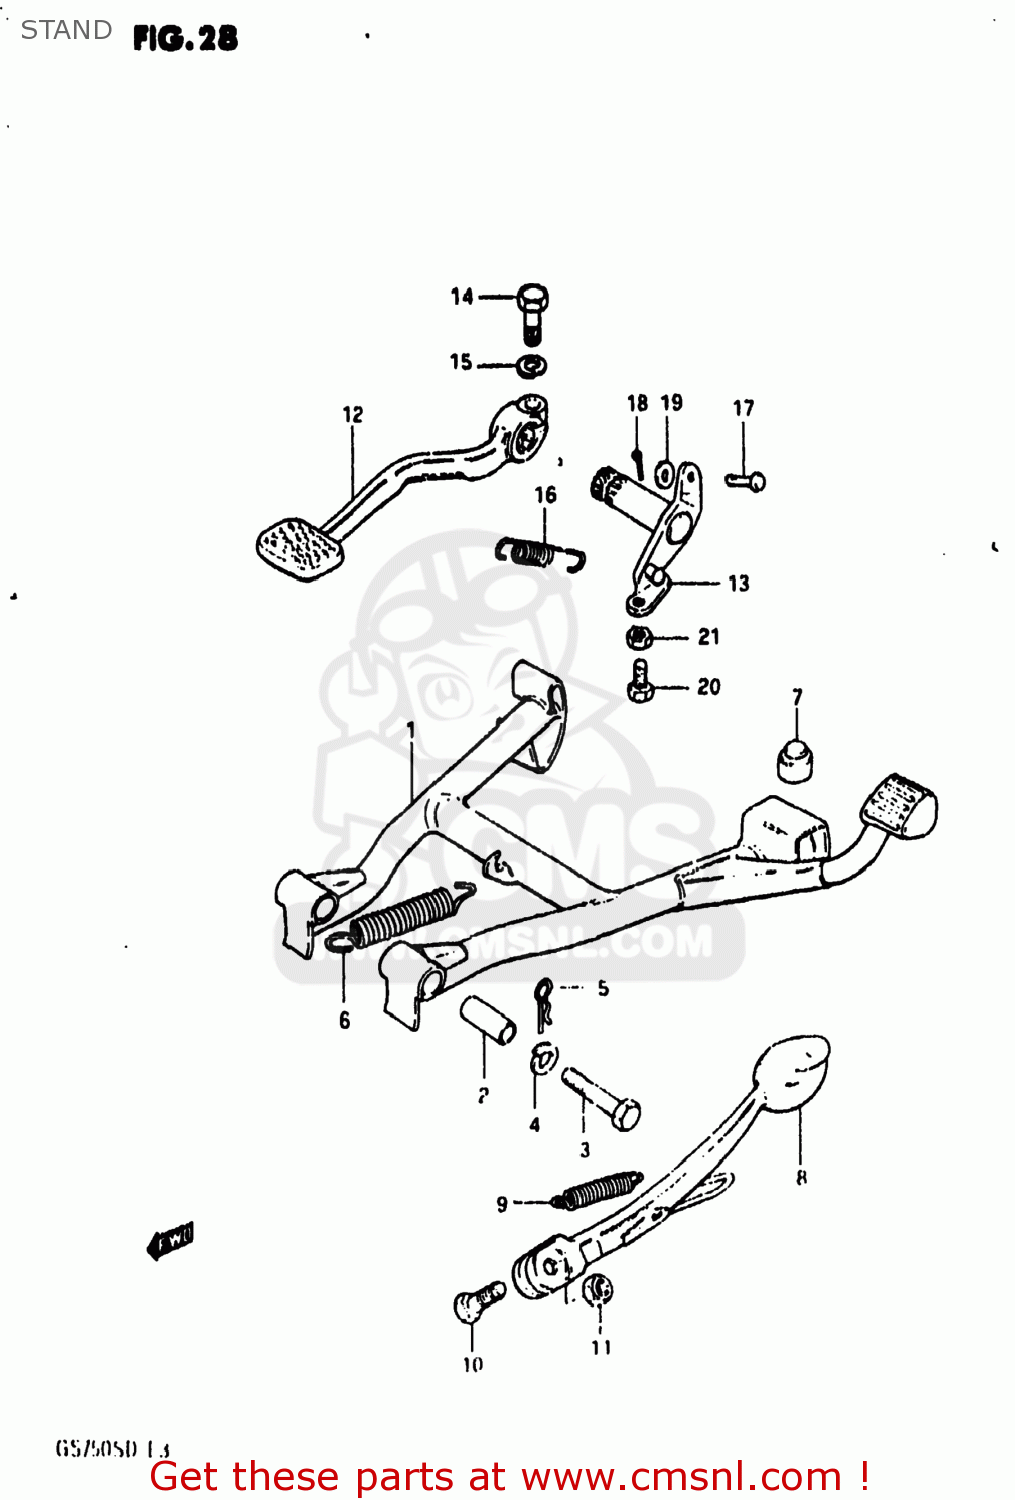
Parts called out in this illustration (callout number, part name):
1	STAND,CENTER
2	SPACER(10X16X38.8)
3	BOLT
4	LOCK WASHER
5	CLIP
6	SPRING
7	CUSHION
8	STAND,PROP
9	SPRING
10	BOLT(10X30)
11	NUT
12	PEDAL,BRAKE
13	ARM,BRAKE PEDAL
14	BOLT (8X30)
15	LOCK WASHER
16	SPRING
17	PIN
18	PIN
19	WASHER
20	BOLT
21	NUT
